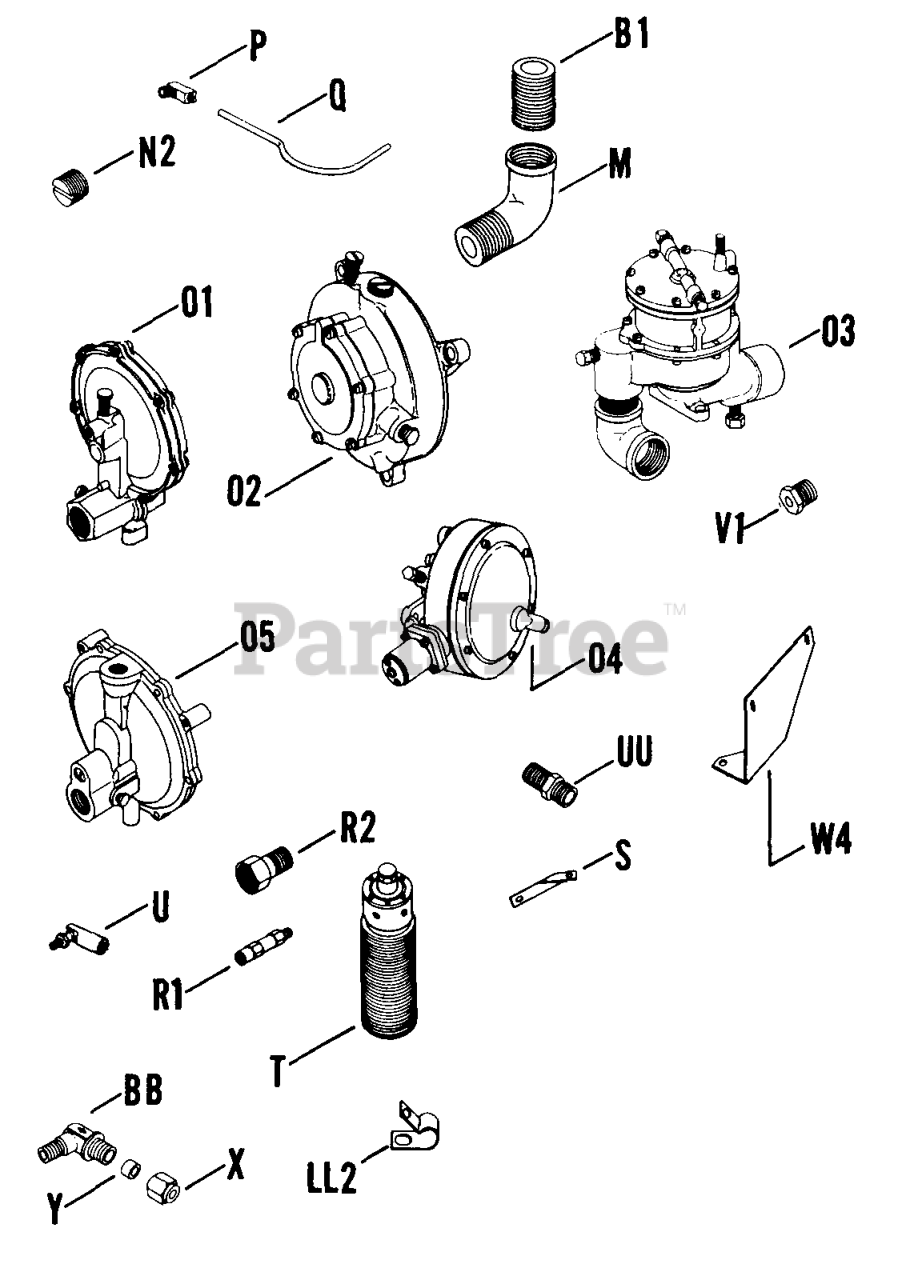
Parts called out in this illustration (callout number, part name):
B1	PIPE - USE 46 136 01
V1	HARNESS - DISCONTINUED
X	NUT - (#DSC)
BB	ELBOW - (#DSC)
